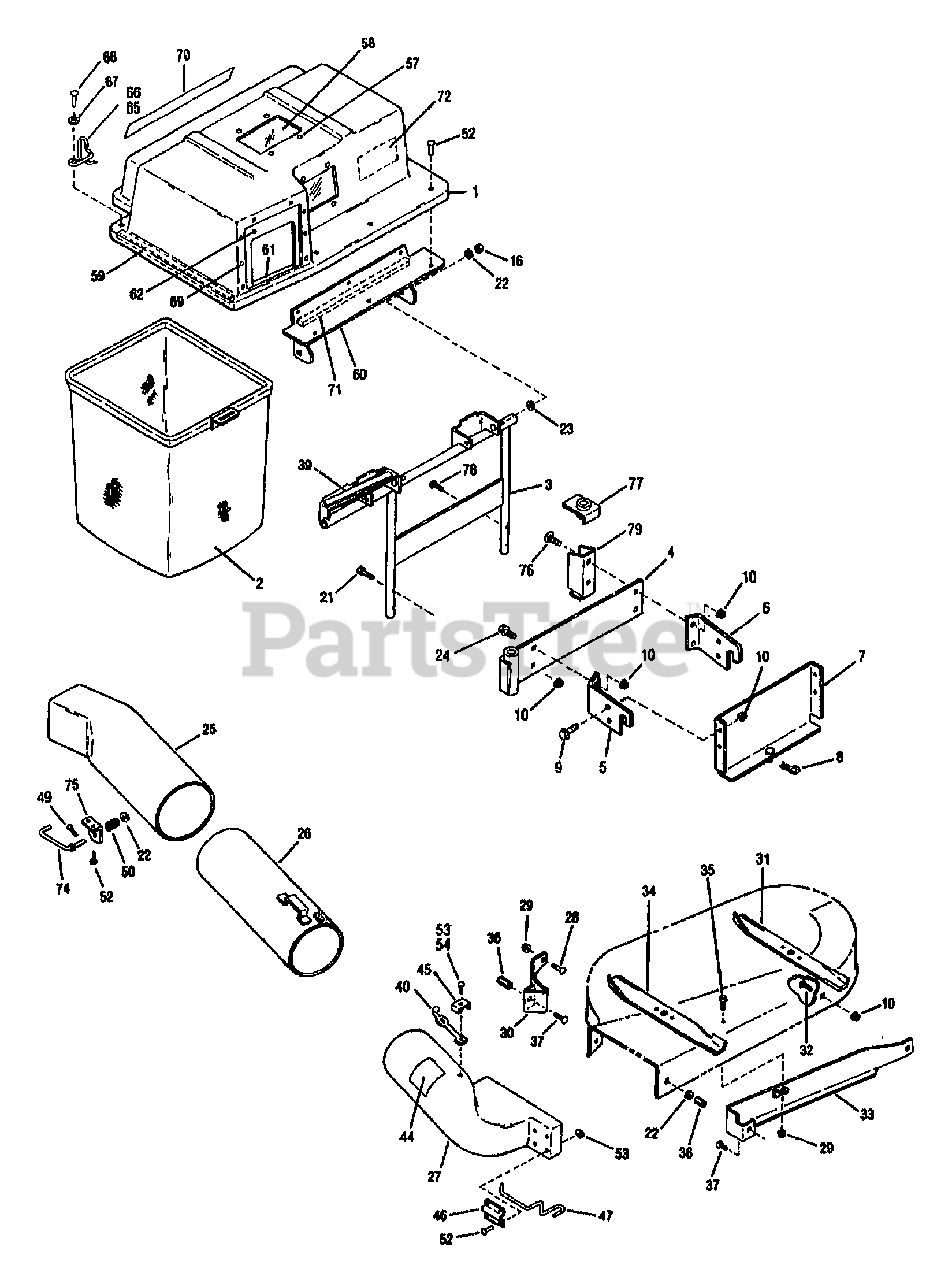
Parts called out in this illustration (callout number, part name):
1	ASSM-CVR GRASS BAG
2	GRASS BAG ASSY.
3	ASSM-BAG SUPPORT
4	ASSM-SUPPORT PLATE
5	PLATE-RIGHT HITCH
6	PLATE-HITCH LH
7	ASSM-SUPPORT HITCH
8	PIN-HITCH .125X2.56 ZP
9	SCR-HFLK 5/16-18X.75 ZP
10	NUT-HFLK 5/16-18 ZP
16	NUT-TOP/LK 5/16-18 ZP
21	SCR HFLK 5/16-18X2.00 ZP
23	WASHER-.87X.34X.06 NYLON
24	SCR-HFLK 5/16-18X1.00 ZP
25	ELBOW
26	ASSM-GRASS GUIDE
27	ASSM-DISCHARGE CHUTE
28	SCR-CARR 1/4-20X.75 G2 ZP
29	NUT-HF/LK 1/4-20 ZP
30	BAFFLE-REAR
31	BLADE-MWR LH HILIFT
33	BAFFLE-FRONT
34	BLADE-MWR RH HILIFT
35	SCR-HH 1/4-20X.625
36	NUT GUIDE 5/16-18 ZP
39	SEAL-COVER 9.5"
40	LATCH-RUBBER
44	DECAL-WARNING
46	LEVER-CLAMP
47	LEVER-LOCK
50	SPRING
52	RIVET-POP 3/16"DIA
53	WASHER-.505X.22X.05
54	POP-RIVET
57	RIVET-POP
58	WINDOW
59	SEAL-COVER
60	ASSM-HINGE SUPPORT
61	CHUTE REINFORCEMENT
62	GASKET-CHUTE
65	COVER-LOCK RH
66	COVER-LOCK LH
67	WASHER-.88X.2X.059
68	RIVET-POP 3/16X1/2
69	RIVET-POP .125
70	DECAL-LOGO
71	SEAL-COVER
72	DECAL-INST
75	BRACKET-CHUTE
77	ASSM-COLLAR STOP
78	SCR
79	SUPPORT-TUBE
